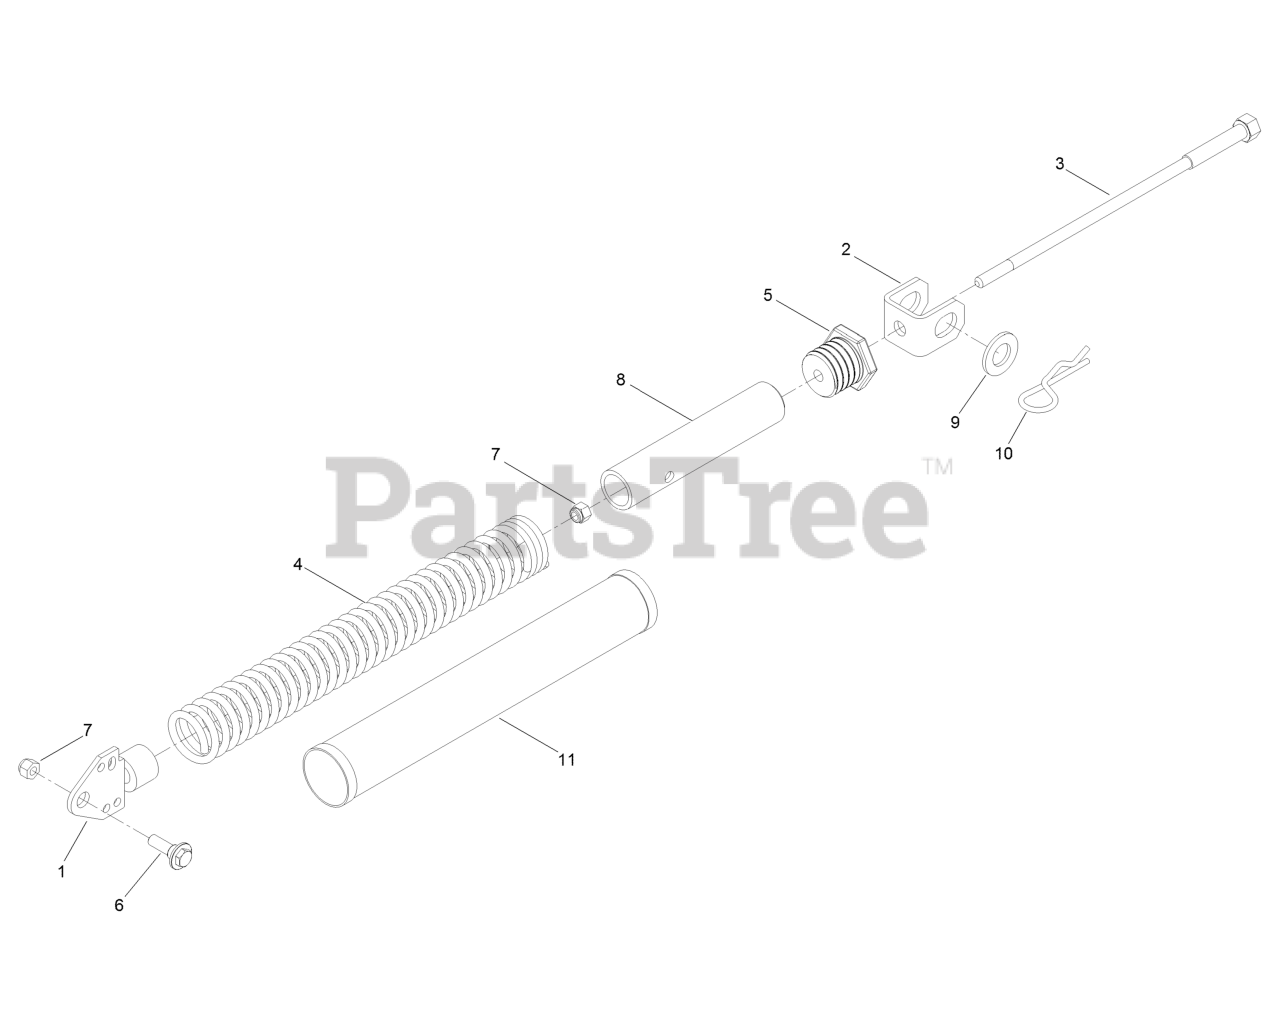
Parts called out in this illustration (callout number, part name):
1	Tensioner-Spring
2	Mount-Lift Assist, Deck
3	Shaft-Adjustment, Spring
4	Spring-Extension
5	Plug-Adjuster, Spring
6	Screw-Shoulder, HWH
7	Nut-Lock, NI
8	Spring-Tube
9	Washer-Flat
10	Pin-Cut Height
11	Cover-Spring, Deck
